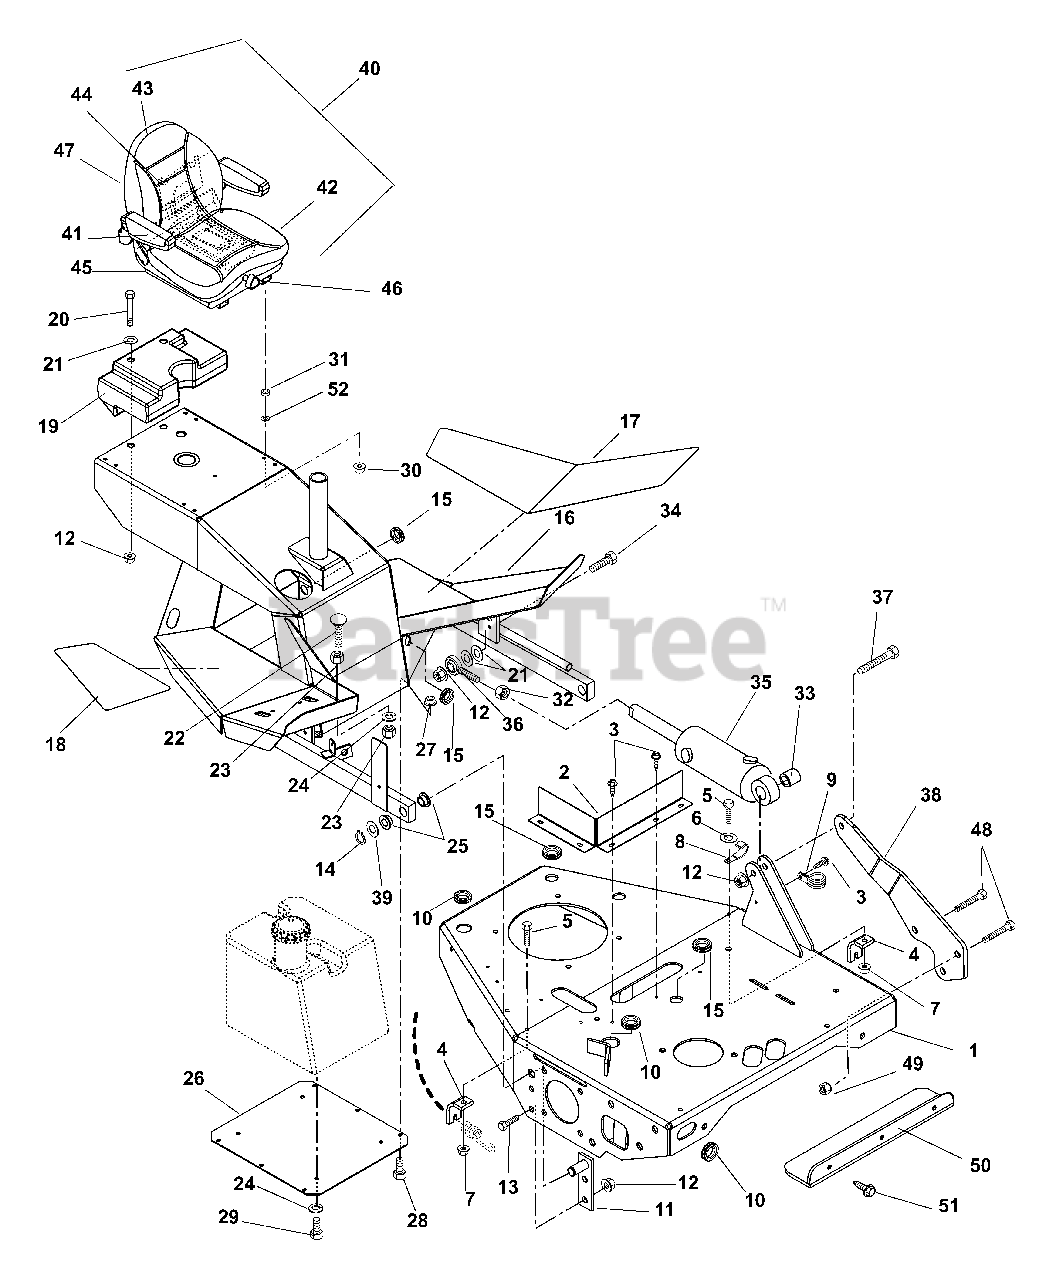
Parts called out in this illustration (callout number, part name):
1	Weldment, Frame
2	Heat Shield
3	Screw-Tapping .25-20 x .50 Hex Washer Head
4	Bracket, Cable
5	Bolt-Hex .31-18 x 1.00 Grade 5
6	Washer-Flat-Steel .344 x .688 x .065
7	Nut-Locking-Top-Flange .31-18
8	J-Clamp
9	Clamp, Steel 1.0
10	Grommet 1.25
11	Weldment, Pivot
12	Nut-Locking-Top-Flange .50-13
13	Bolt-Hex .50-13 x 1.50 Grade 5
14	Ring-Retaining-External .689 x .077
15	Grommet .75 x 1.06 x 1.38
16	Weldment, Sulky
17	Pad, Left Hand Floorboard
18	Pad, Right Hand Floorboard
19	Weight, Rear
20	Bolt-Hex .50-13 x 4.00 Grade 5
21	Washer-Flat-Steel .531 x 1.06 x .095
22	Bolt-Round Head Square Neck .31-18 x 1.50 Grade
23	Nut-Hex .31-18
24	Washer-Locking .31 x .078
25	Bushing, Flange-Nylon .762 x 1.00 x .58 x 1.48
26	Plate, Bottom
27	Nut-Locking-Top-Flange .38-16
28	Bolt-Hex .38-16 x 1.00 Grade 5
29	Bolt-Hex .31-18 x .75 Grade 5
30	Nut-Locking-Top-Flange .31-18
31	Bushing-Sleeve .377 x .624 x .235
32	Nut-Jam .50-20 Grade 2
33	Bushing, .516 x 1.00 x 1.05
34	Bolt-Hex .50-13 x 2.25 Grade 5
35	Cylinder, Platform Lift
36	Assembly-Rod End Right Hand
37	Bolt-Hex .50-13 x 2.75 Grade 5
38	Support, Cylinder Brace
39	Washer-Hardened-Thrust .758 x 1.23 x .031
40	Seat-Suspension
41	Kit-Arm Pad
42	Kit-Cushion
43	Kit-Seatback
44	Kit-Spring and Saddle
45	Kit-Seat Slide
46	Kit-Seat Knob
47	Kit-Seat Back Panel
48	Bolt-Hex .62-11 x 1.75 Grade 5
49	Nut-Locking-Center .62-11
50	Guard, Hose
51	Screw-Tapping .25-20 x .50 Hex Washer Head
52	Nut-Push .312
